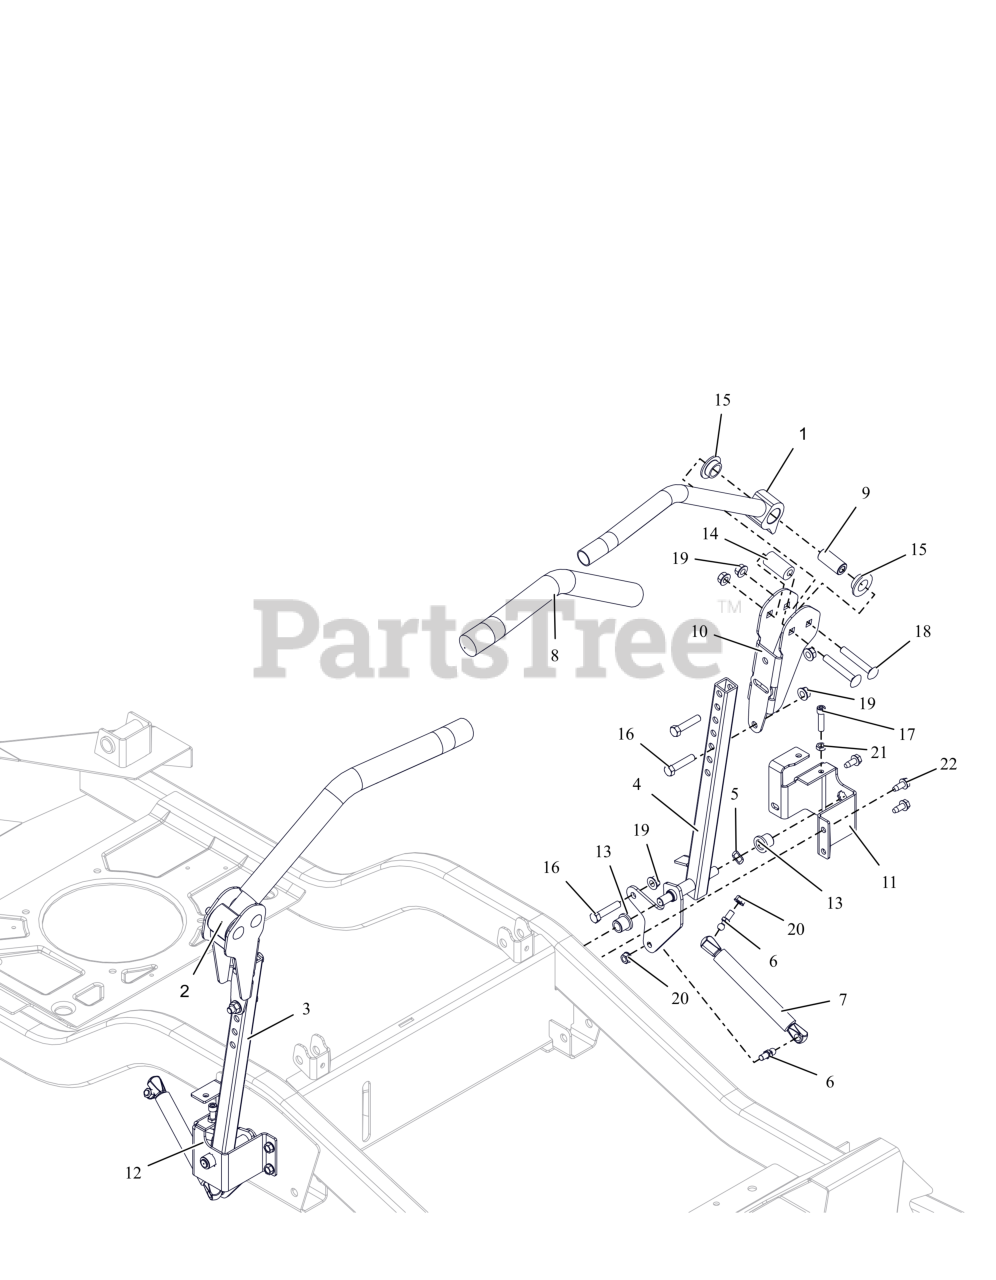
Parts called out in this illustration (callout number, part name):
1	WLDMT, CONTROL HANDLE-LH (BLACK)
2	WLDMT, CONTROL HANDLE-RH (BLACK)
3	WLDMT, STEERING RH
4	WLDMT, STEERING LH
5	WAVE WASHER .531X.781X.125FH
6	STUD- BALL
7	DAMPER
8	GRIP, HANDLEBAR
9	SPACER, STEERING ARM
10	ADJ UPPER CONTROL ARM BRKT-BLK
11	BRKT, STEERING ARM MOUNT -LH
12	BRKT, STEERING ARM MOUNT -RH
13	BHSG-FLG .500X.750X.750X.125
14	BSHG, ECCENTRIC.406X.875X1.625
15	BSHG-FLG .762X1.48X.44 NYL
16	BLT, HEX .38-16X1.75 G5 ZCC
17	BLT, SHCS .312-18X1.25 G8 SS
18	BLT, RHSSN.38-16X2.50 G5 ZCC
19	NUT-LK-TOP-FLG .38-16 ZC120
20	NUT,LK-CTR-FLG .31-18 GF ZCC
21	NUT-JAM .312-18 G2 ZCC
22	SCR,TAP .312-18X.75 HWH TR ZCC
